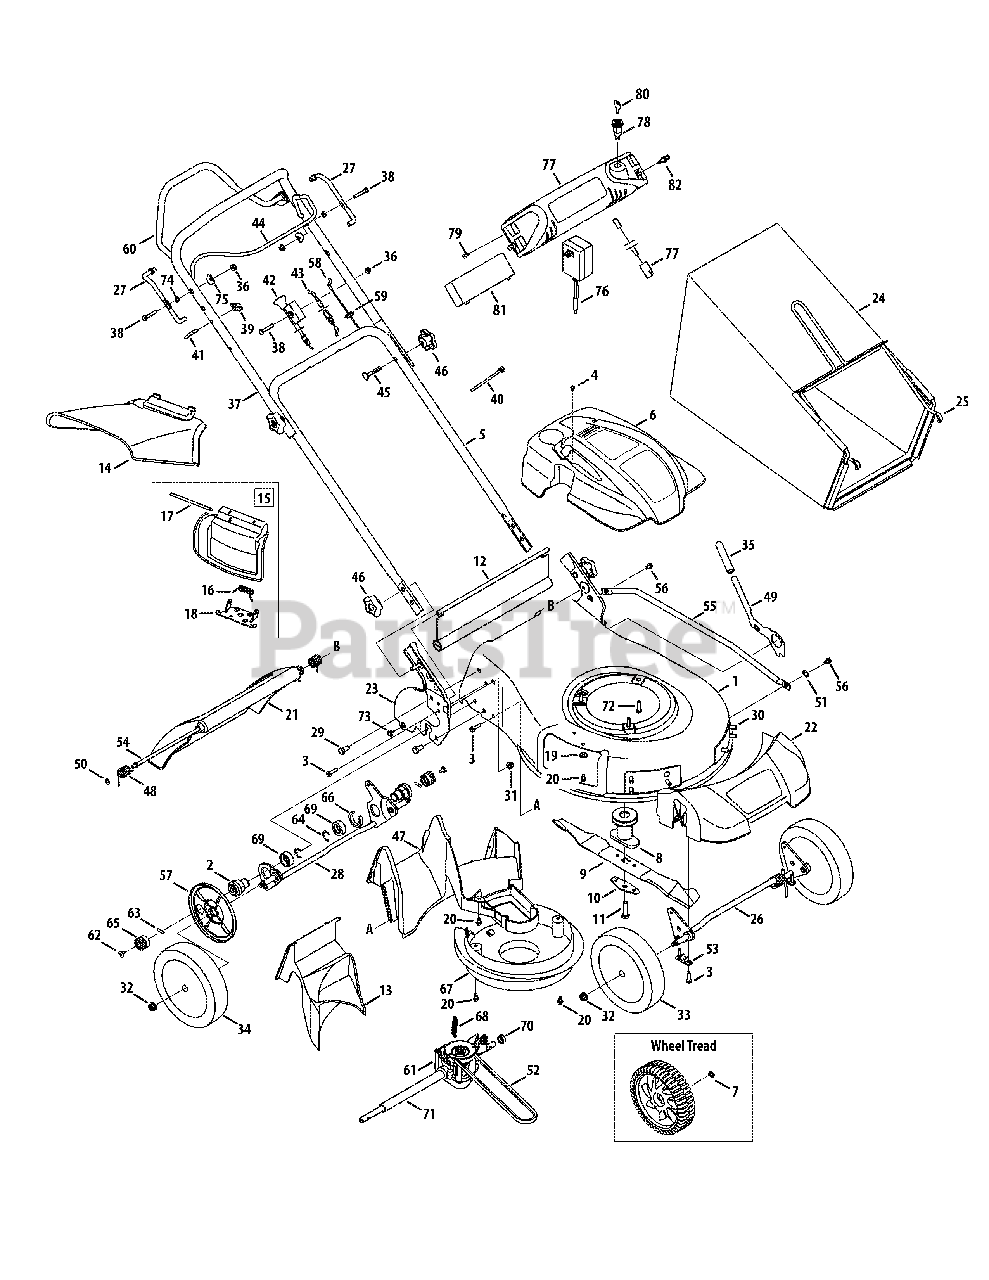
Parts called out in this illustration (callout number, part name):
2	Transmission Support Bearing
3	Screw, 1/4-15 x 1.000
4	Screw, Machine, M4-.7 x 10.00
6	Engine Shroud
7	Washer, Wave, .510 x .750 x .017
8	Blade Adapter
9	Mulching Blade
10	Blade Bell Support
11	Screw, 3/8-24 x 1.50
12	Trailing Shield
13	Rear Mulch Plug
14	Side Discharge Chute
15	Mulch Plug (Incl. 16-18)
16	Torsion Spring
17	Hinge Pin
18	Chute Deflector Adapter
19	Beleville Washer
21	Rear Door
22	Front Cover
27	Drive Control Pivot Rod - LH
27	Drive Control Pivot Rod - RH
29	Hhcs, 5/16-18 x .625
30	Screw, 5/16-14 x .750
31	Nut, Flange Lock, 5/16-18
32	Nut, Flange Lock, 3/8-16
33	Front Wheel
34	Rear Wheel
35	Foam Grip
36	Nut, Flange Lock, 1/4-20
38	Screw, 1/4-20 x 1.50
40	Cable Tie
41	Rope Guide
42	Choke Cable
43	Control Cable
44	Blade Control
45	Bolt Carriage, 5/16-18 x 2.0
46	Star Knob
47	Rear Baffle
48	Door Torsion Spring - RH
48	Door Torsion Spring - LH
49	Spring Lever
51	Washer, Wave, .390 x .825 x .016
52	V-Belt
53	Bushing, Lock, .505 Dia. X .62
54	Rear Door Pivot Rod
56	Scr., Shldr., 1/4-20 x .50
57	Wheel Dust Cover
58	Drive Cable
60	Drive Control
61	Transmission
62	Screw, 1/4-20 x .390
63	Dowel Pin
64	Retainer Ring
65	Spur Gear - RH
65	Spur Gear - LH
66	Spacer, Clip
67	Engine Baffle
68	Extension Spring, .429OD x 2.515
69	Bearing Support Spacer
70	Sleeve Spacer, .550ID x .340 Lg.
71	Sleeve Spacer, .550ID x 7.97 Lg.
72	Screw, 3/8-16 x 1.00
73	Screw, #10-16 x .500
74	Washer, Lock, 1/4
75	Washer, Saddle
76	Battery Charger
77	Electric Start Harness Assembly
78	Key Switch
79	Screw, #10-16 x .750
80	Key
81	Battery
